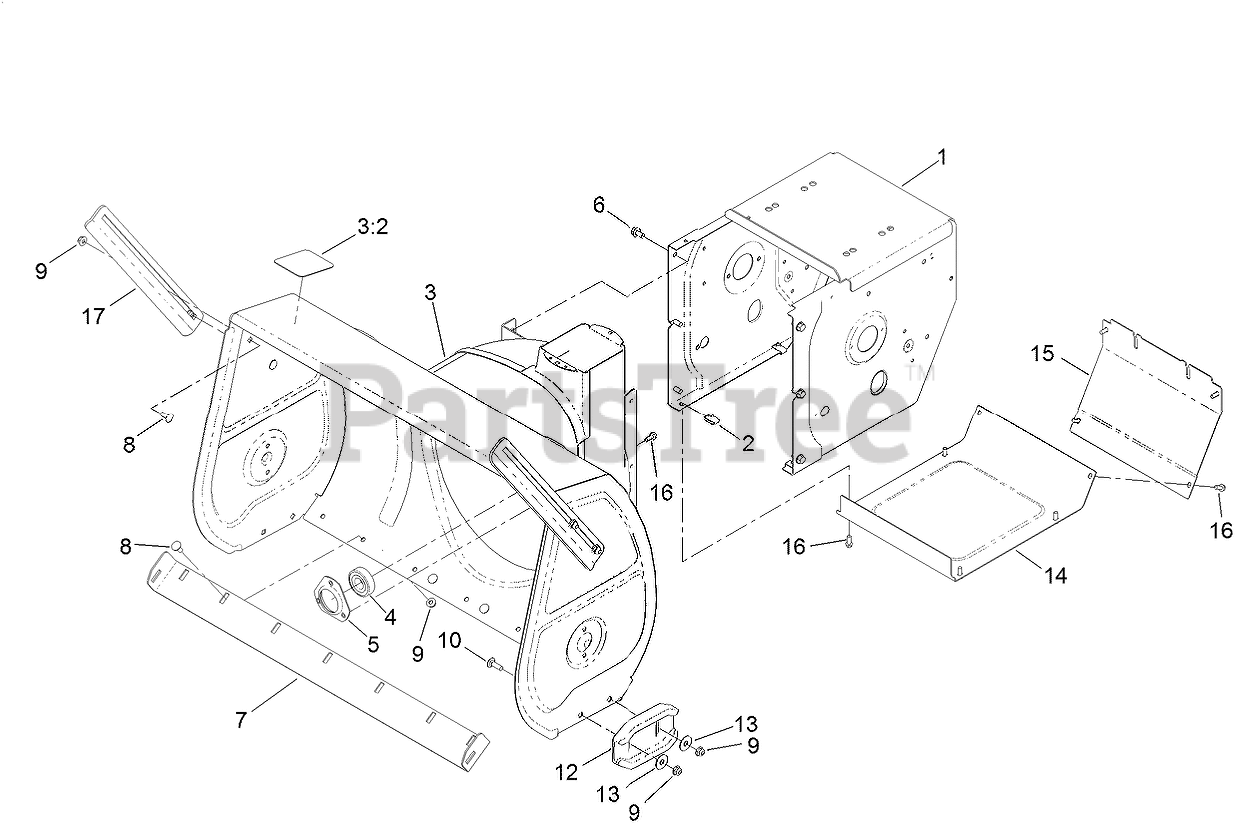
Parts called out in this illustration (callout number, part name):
1	FRAME-TRACTION
3	AUGER HOUSING ASM
3:2	DECAL-DANGER, AUGER
4	BEARING-BALL
5	RETAINER-BEARING
6	SCREW-HWHTF
7	BLADE-SCRAPER
8	BOLT-CARR
9	NUT-HF
10	BOLT-CARR
12	SKID-CAST
13	WASHER-FLAT
14	COVER-BOTTOM
15	COVER-REAR
16	SCREW-HWH
17	BREAKER-DRIFT, SIDE
